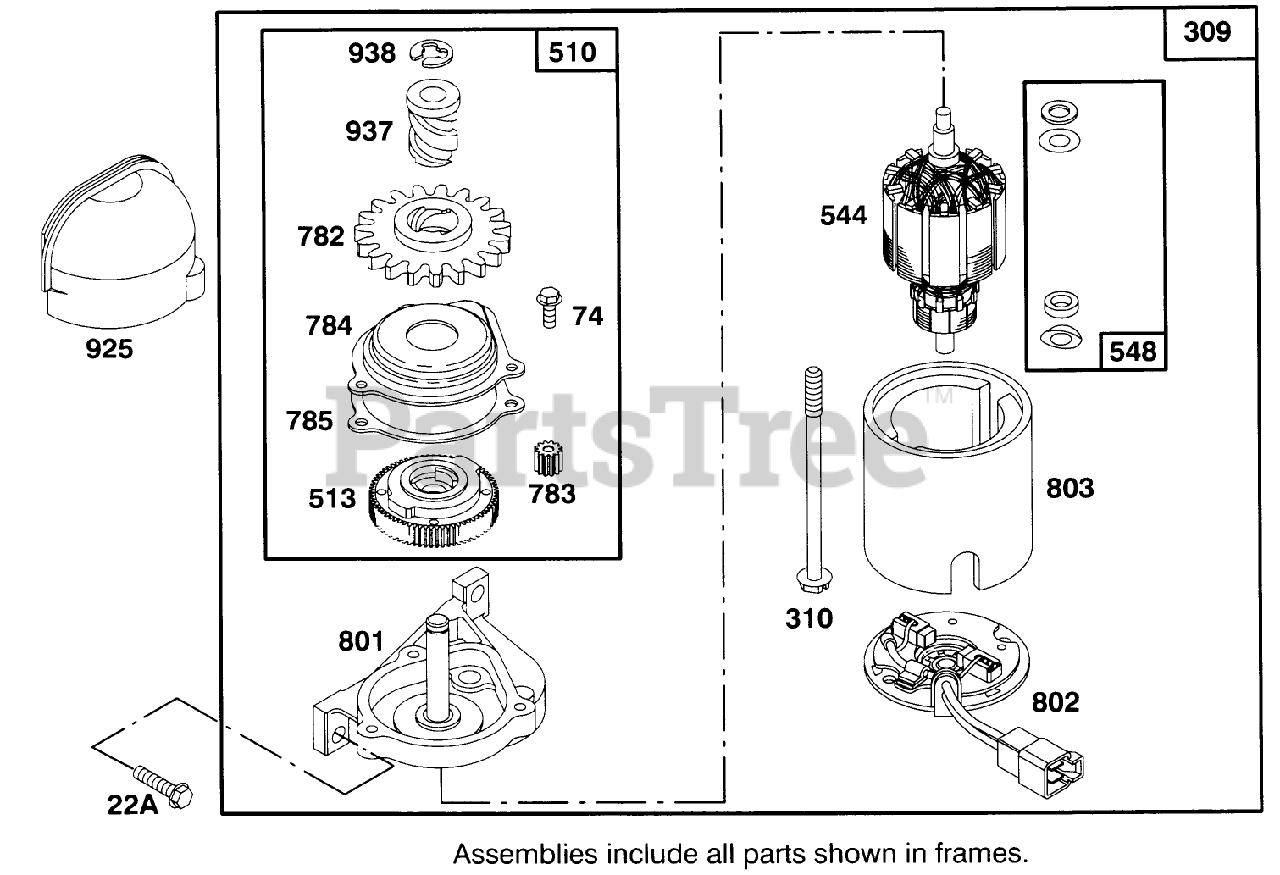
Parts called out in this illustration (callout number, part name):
22A	SCREW - CARBUERTOR MTG
510	DRIVE SET
513	CLUTCH - STARTER
548	WASHER ASSEMBLY
782	GEAR - STARTER
925	COVER - STARTER
938	RETAINER - LOCK
